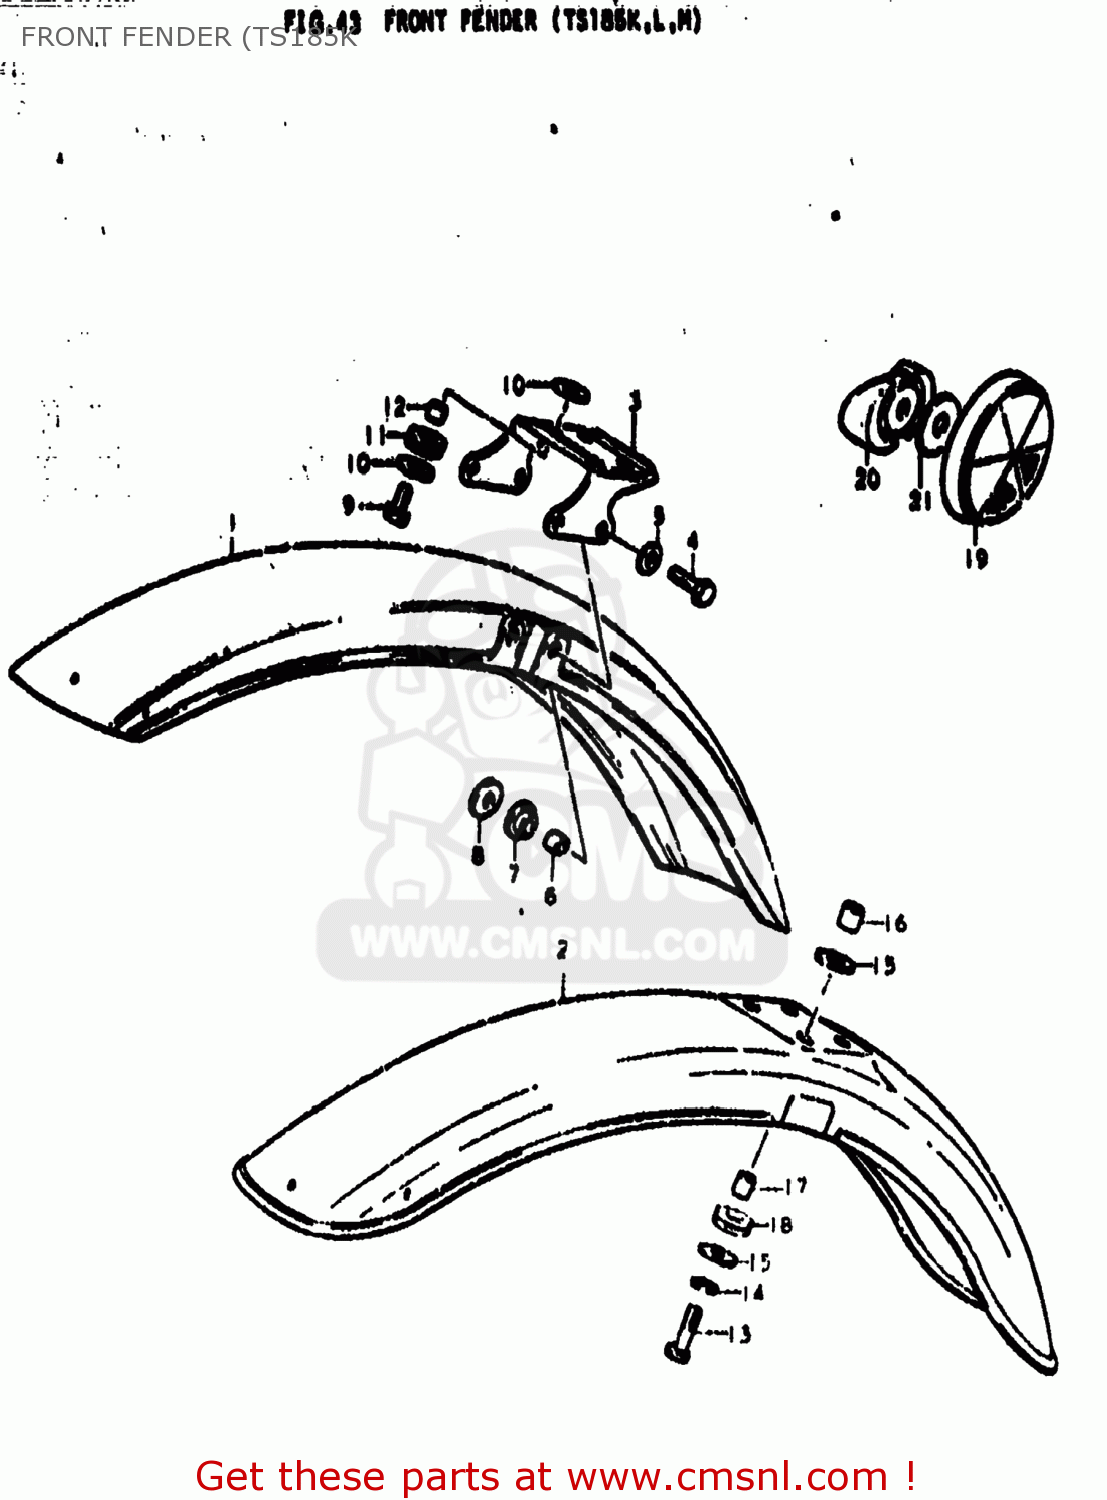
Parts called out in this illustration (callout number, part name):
1	FENDER,FRONT
2	FENDER,FRONT
3	BRACE,FRONT FENDER
4	BOLT(6X18)
5	WASHER
6	SPACER
7	CUSHION
8	WASHER (6.5X20X1.2)
9	BOLT
10	WASHER (6.5X20X1.2)
11	CUSHION
12	SPACER(6.1X9X7.5)
13	BOLT
14	LOCK WASHER
15	WASHER (6.5X24X1.2)
16	SPACER (6.8X10X20)
17	SPACER (6.5X10.5X13.5)
18	CUSHION
19	REFLEX REFLECTOR ASSEMBLY
20	SPACER
21	WASHER
